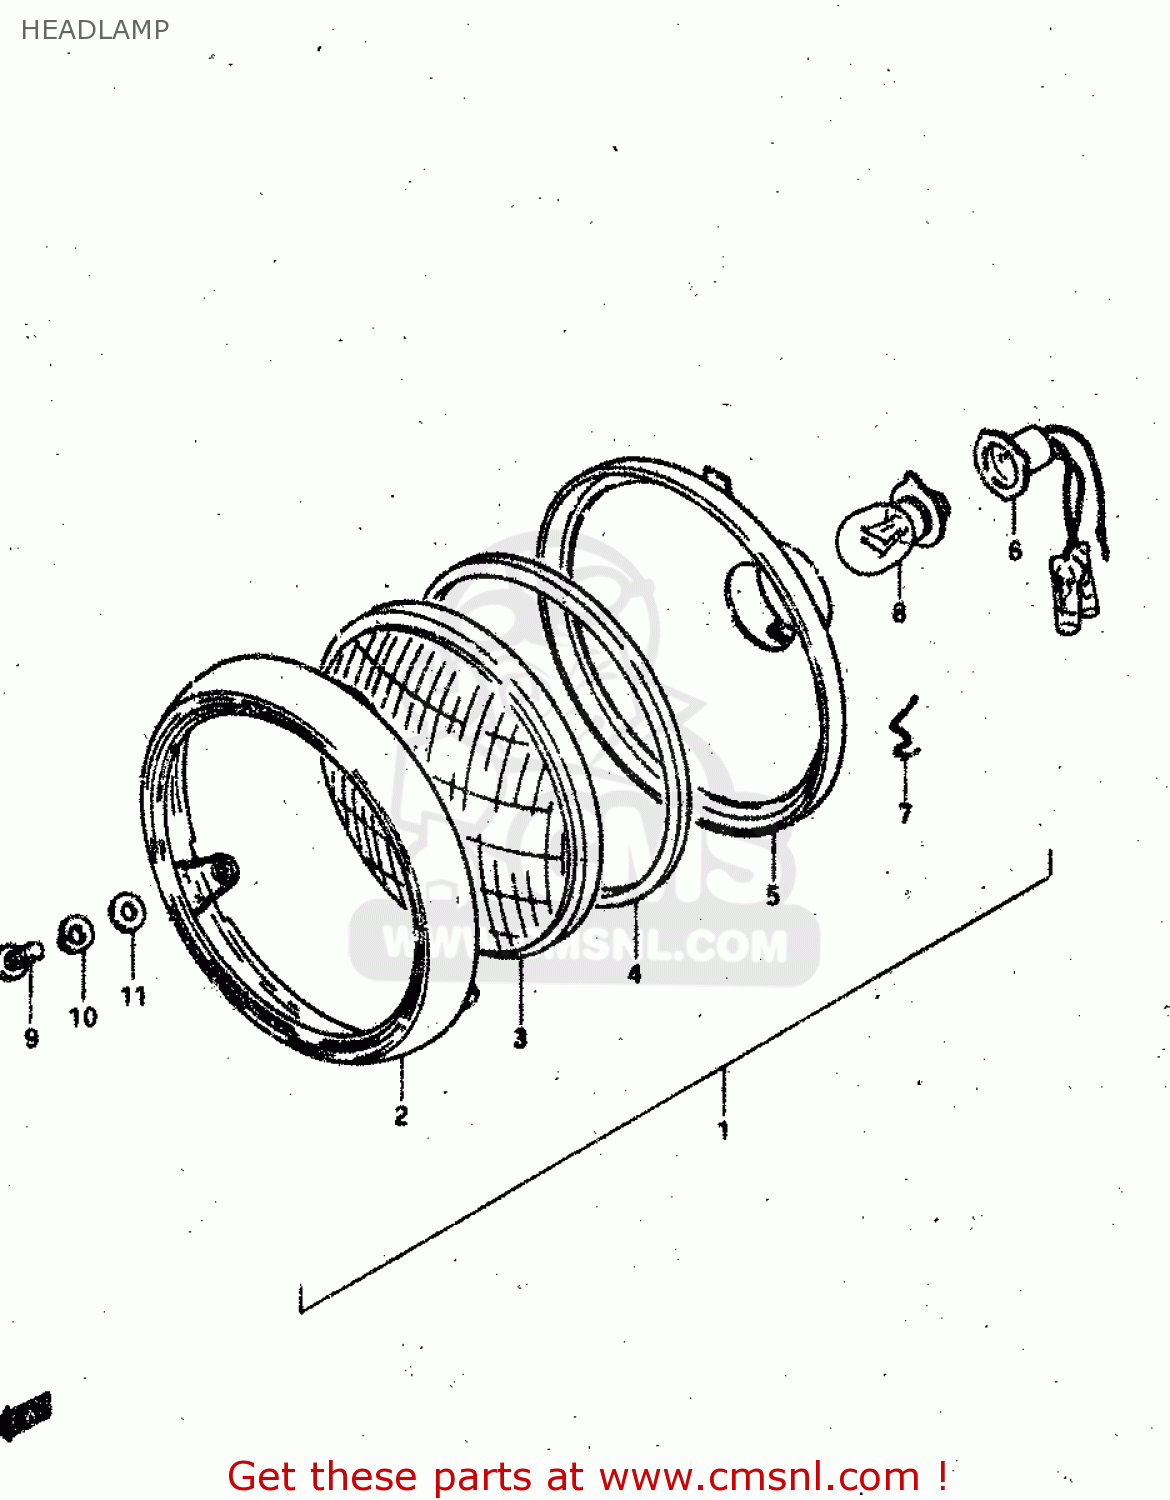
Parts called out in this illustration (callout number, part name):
1	HEADLAMP ASSY
2	RIM
3	LENS
4	GASKET (NAS)
5	REFLECTOR
6	SOCKET,HEADLAMP
7	SPRING
8	BULB(6V15/15W/STANLEY,A3598HA)
9	SCREW
10	LOCK WASHER
11	WASHER
